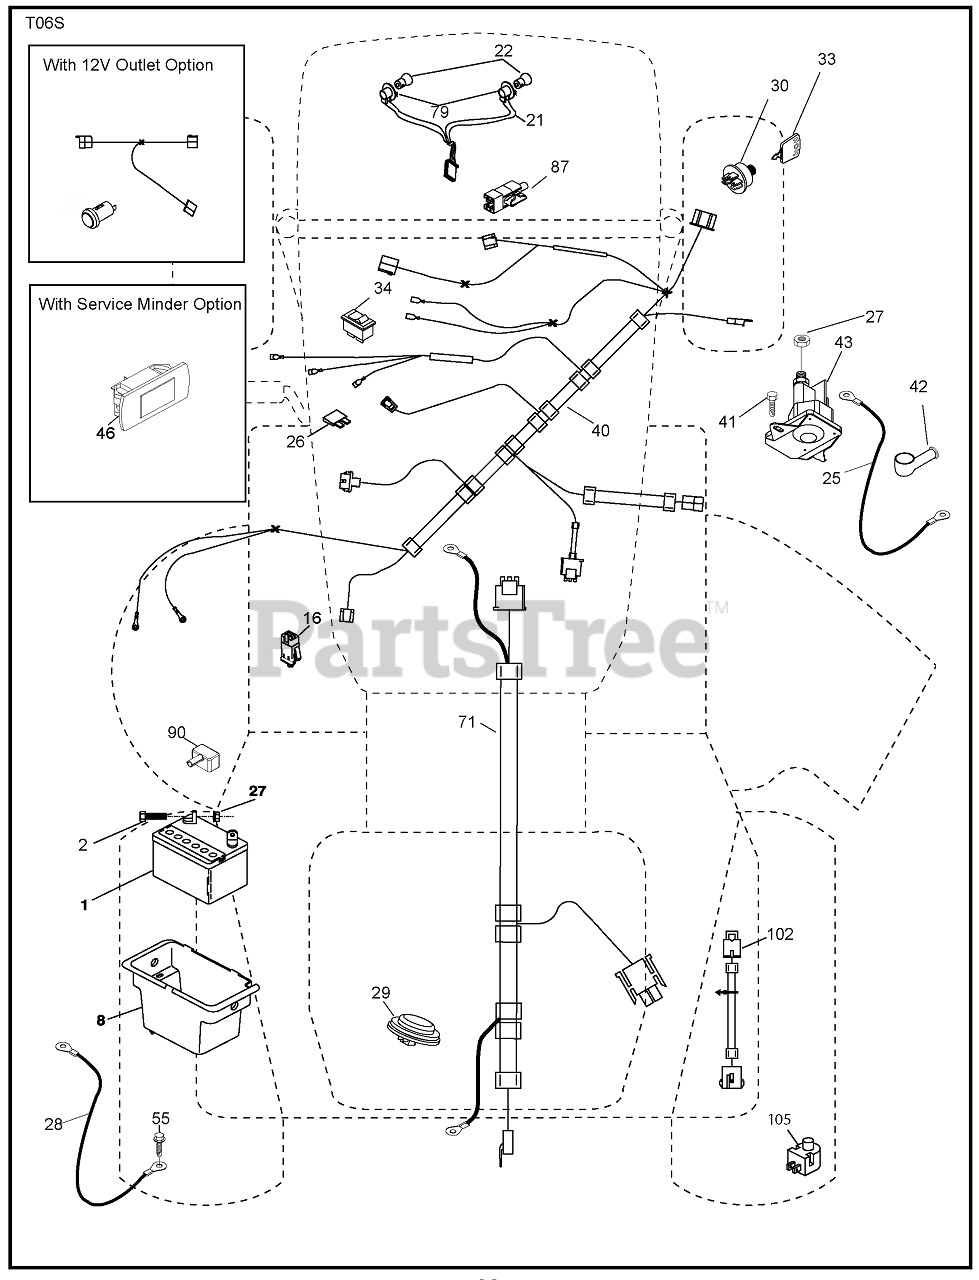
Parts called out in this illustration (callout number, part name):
1	Battery
2	Bolt Hex Head 1/4-20 x 3/4
8	Box Battery
16	Switch Interlock Push-In
21	Harness Socket Light w/4152J
22	Bulb Light
25	Cable Starter
26	Fuse
27	Nut Keps Hex 1/4-20 unc
28	Cable, Ground
29	Switch, Seat
30	Switch, Ign
33	Key/Chain
34	Switch Light/Reset
40	Harness Ign. Dash
41	Screw Thd Cut 1/4-20 x 1/2
42	Cover, Terminal
43	Solenoid
46	Gauge Serviceminder Hrmtr
55	Screw Thdrol 5/16-18 x 3/4 TYTT
71	Harness Ign.
79	Socket Asm. Bulb
87	Switch Interlock
90	Cover Terminal
102	Harness Pigtail
105	Switch Reverse
